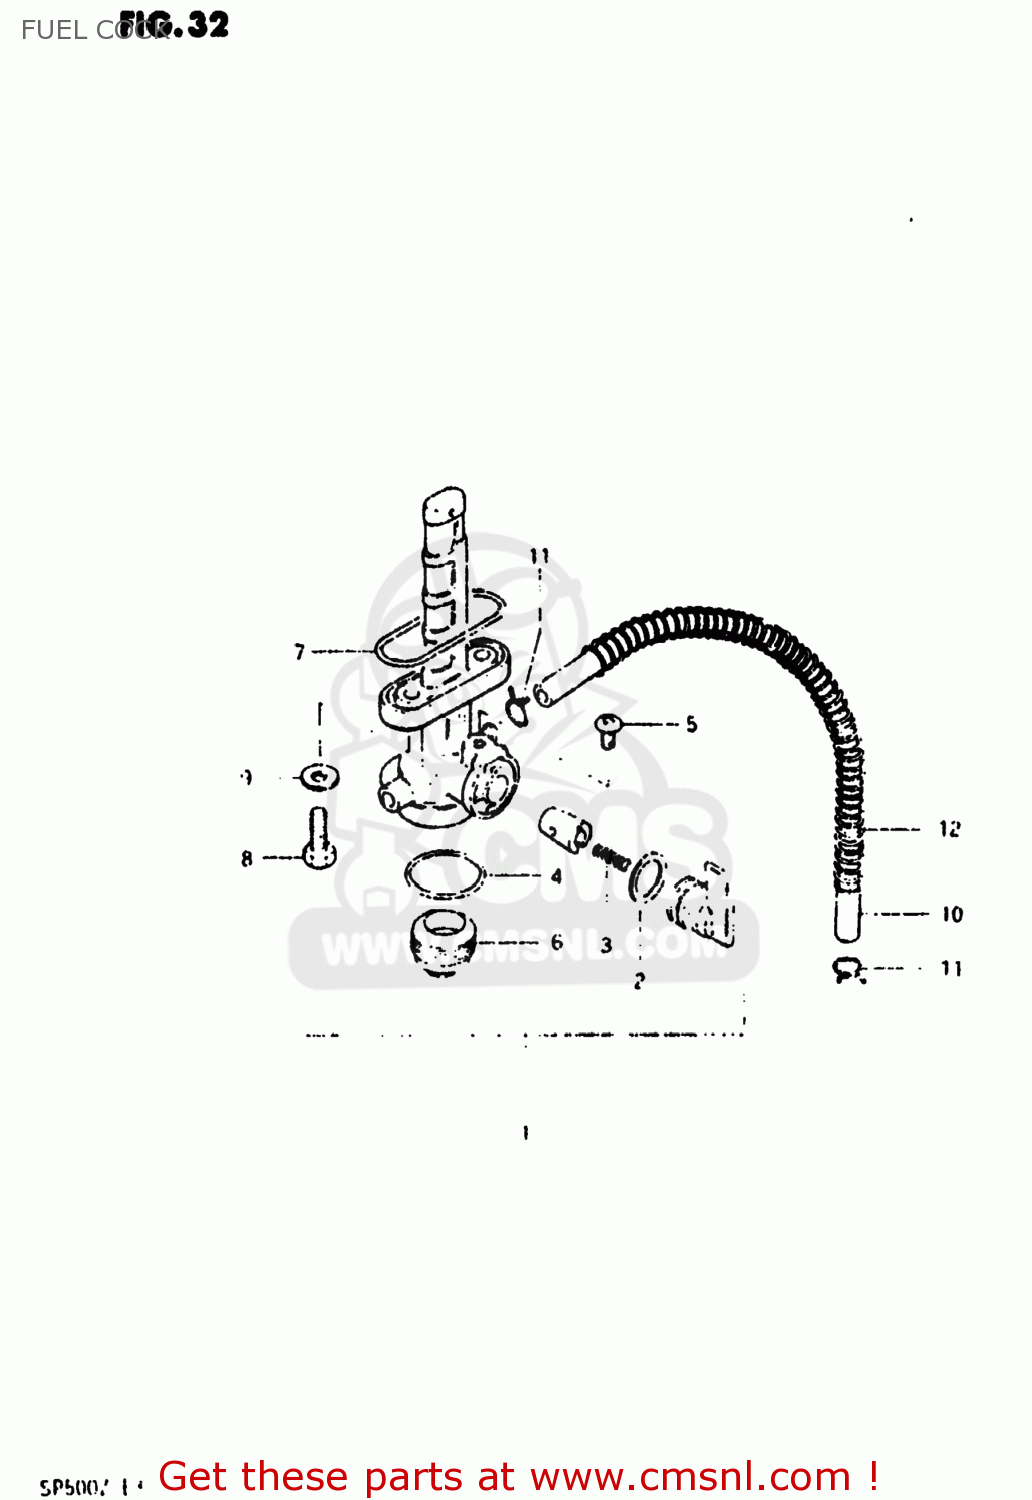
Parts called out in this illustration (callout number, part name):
1	COCK ASSEMBLY,FUEL
2	O-RING
3	SPRING
4	GASKET,FILTER (NAS)
5	SCREW,FUEL COCK LEVER
6	CUP,STRAINER
7	O RING,FUEL COCK
8	BOLT(6X20)
9	GASKET
10	HOSE
11	CLIP
12	SPRING
